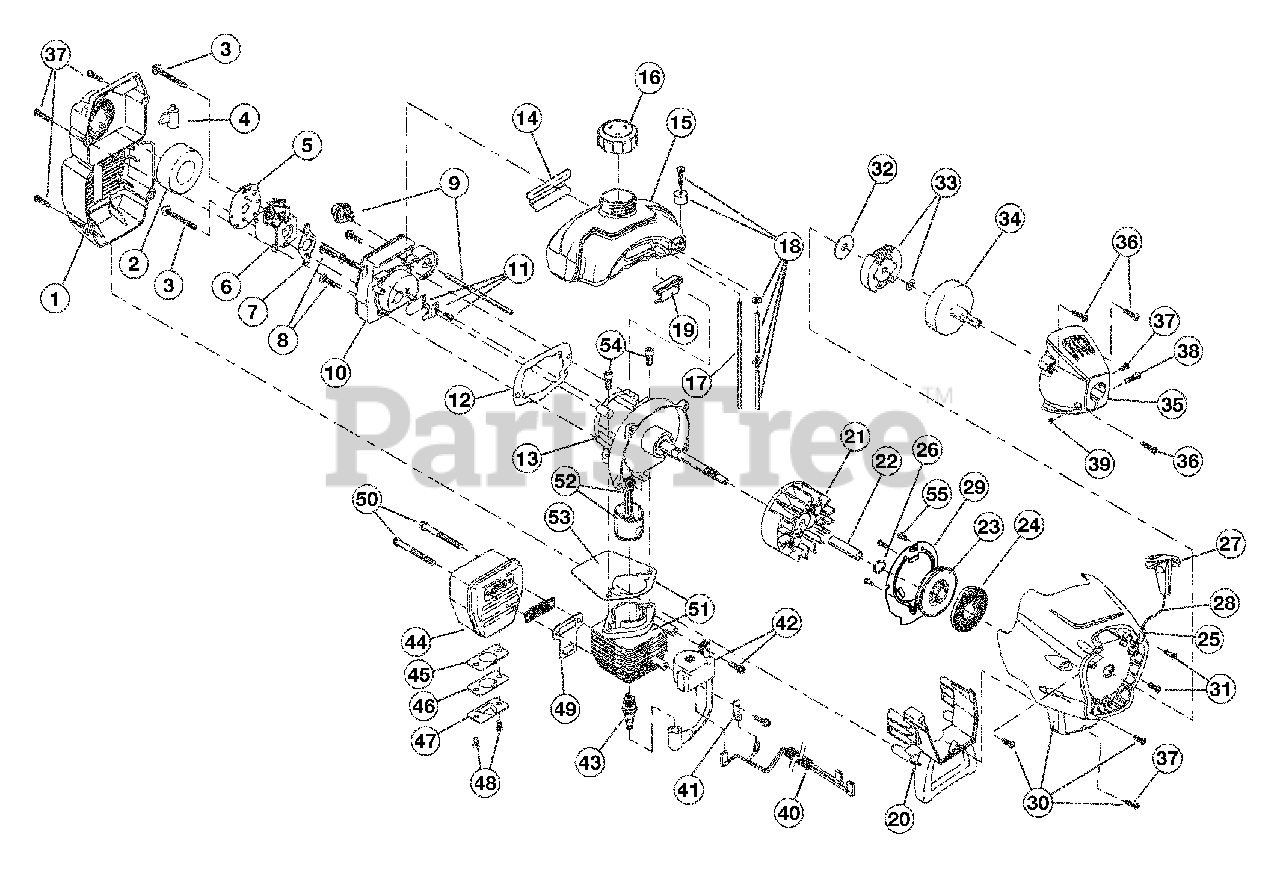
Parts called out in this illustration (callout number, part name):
1	Air Cleaner/Muffler Cover Assembly includes 2 & 36)
2	Air Cleaner Filter
3	Carburetor Mounting Screw Assembly
4	Choke Extension
5	Choke Plate
6	Carburetor Assembly (includes 7 & 18)
7	Carburetor Gasket
8	Carb Mount Screw
9	Primer and Hose Assembly
10	Carb Mount Assembly (includes 8, 11 & 12)
11	Reed Assembly
12	Carburetor Mount Gasket
13	Crank Case Service Assembly includes 8)
14	Rear Mounting Pad
15	Fuel Tank Assembly (includes 16-18)
16	Fuel Cap Assembly
17	Fuel Return Line
18	Fuel Line Assembly
19	Front Mounting Pad
20	Shroud Extension & Stand (includes 36)
21	Flywheel Assembly
23	Recoil Pulley
24	Recoil Spring
25	Rope Guide
26	Pulley Retainer
27	Pull Handle
29	Pressure Plate Assembly (includes 36)
30	Starter Housing Assembly (includes 23-29, 31 & 52)
31	Housing Screw
32	Clutch Washer
33	Clutch Rotor Assembly
34	Clutch Drum Assembly
35	Clutch Cover Assembly (includes 36-39)
36	Cover Screw
37	Anti-Rotation Screw
38	Clamping Screw
39	Clamping Nut
40	Wire Leads and Sleeve
41	Ground Tab
42	Module Assembly
43	Spark Plug
44	Muffler Assembly (includes 45-50)
45	Spark Arrestor Screen
46	Spark Arrestor Plate
47	Spark Arrestor Hood
48	Spark Arrestor Screw
49	Exhaust Gasket
50	Muffler Mounting Bolt Assembly
51	Cylinder Assembly (includes 53 & 54)
52	Piston and Rod Assembly
53	Cylinder Gasket
54	Cylinder Bolt
55	Screw
